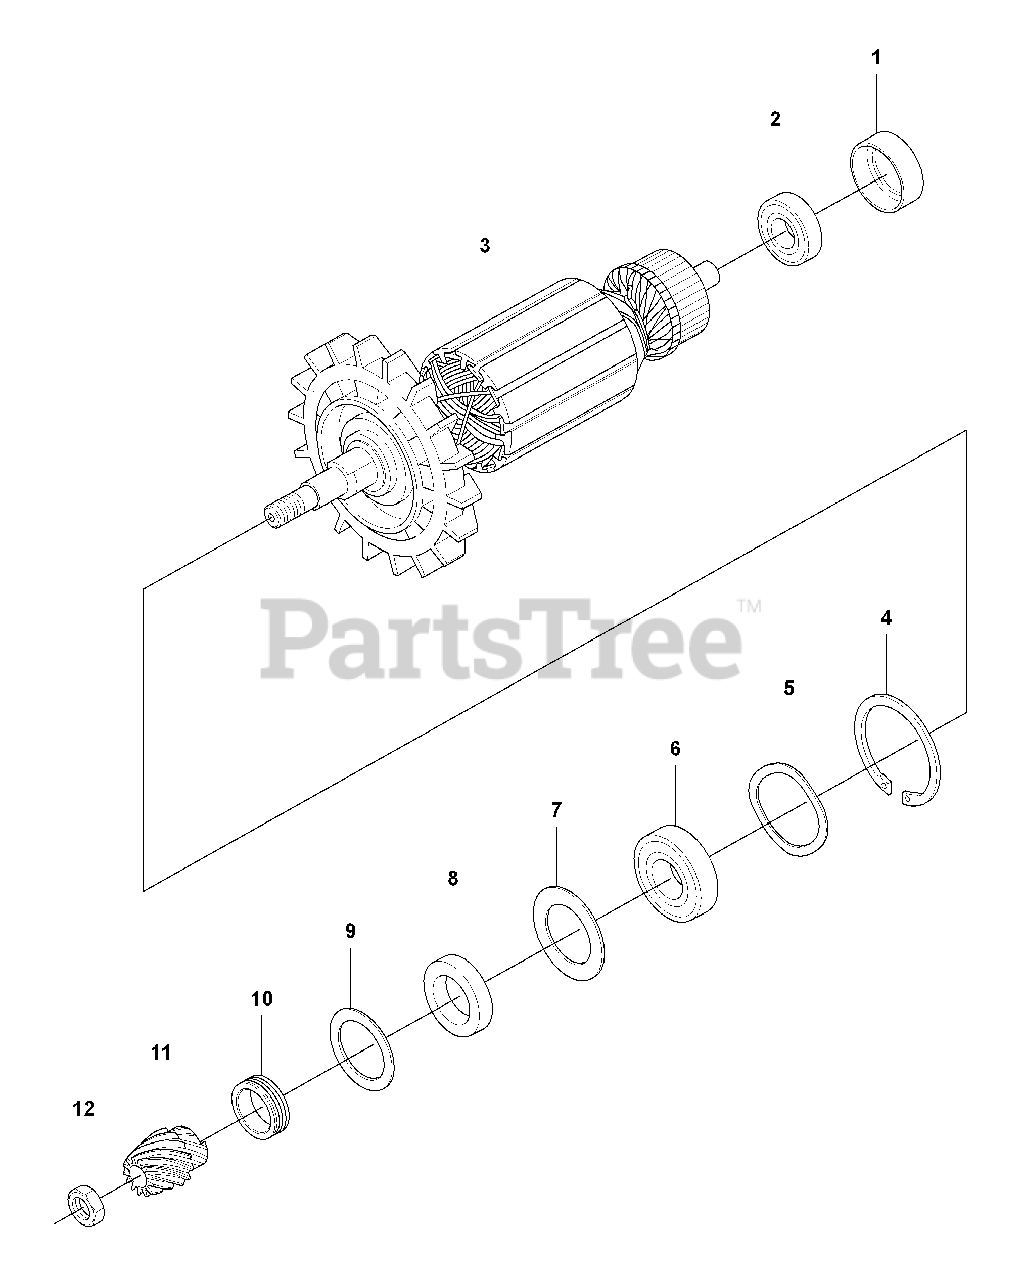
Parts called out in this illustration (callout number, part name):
1	RUBBER BUSHING
2	BALL BEARING
3	ARMATURE
5	SPRING WASHER
6	BALL BEARING
8	FELT JOINT
12	NUT
